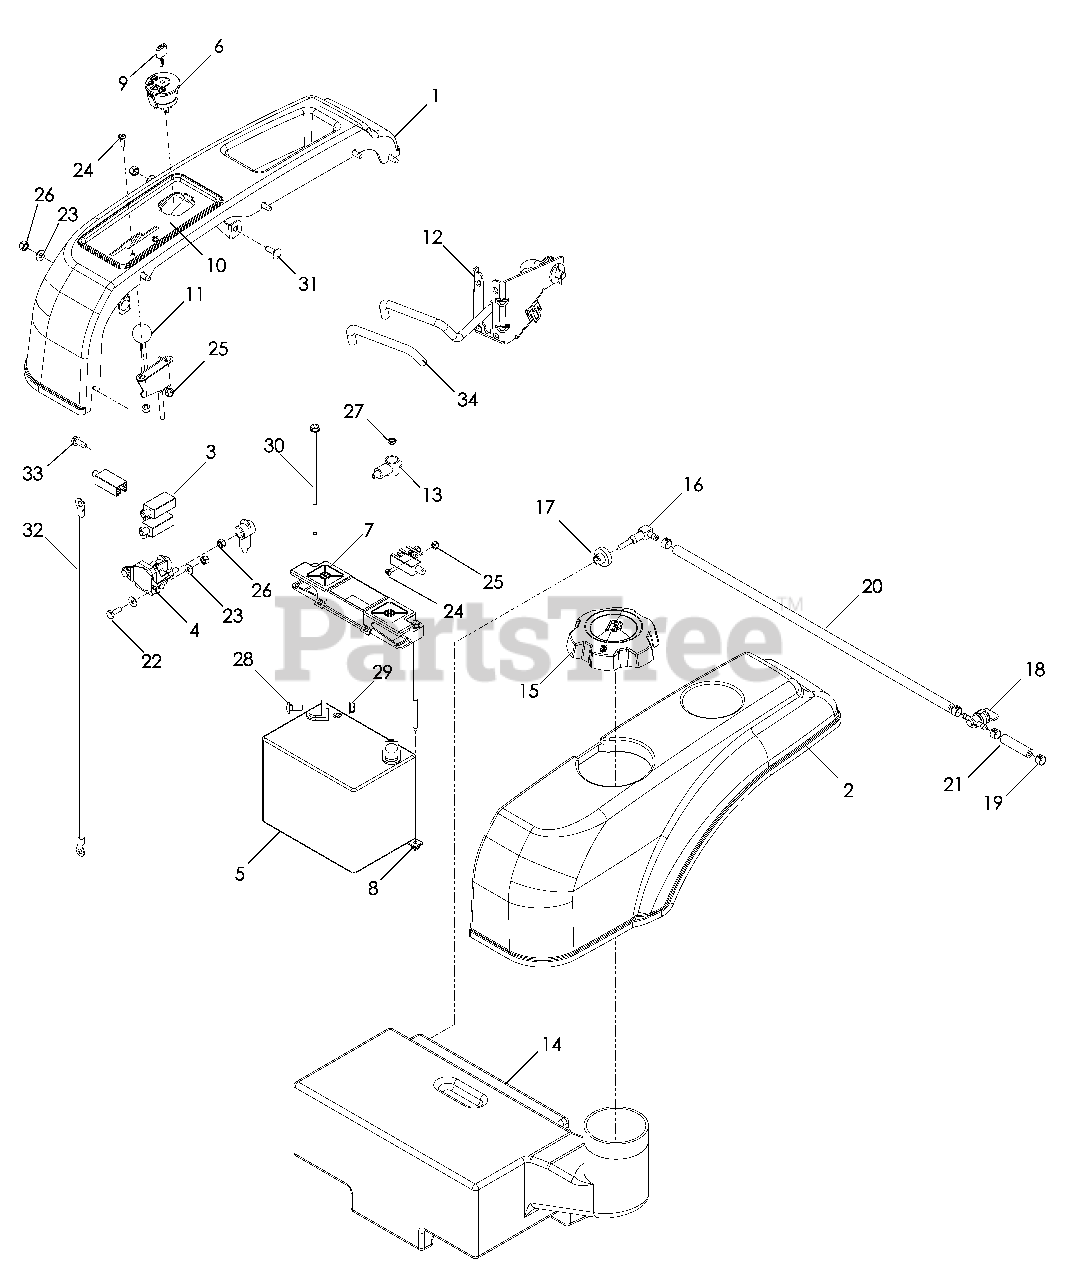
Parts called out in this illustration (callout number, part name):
1	FENDER, RH
2	FENDER, LH
3	SWITCH
4	SOLENOID
5	BATTERY
6	SWITCH, IGNITION
7	BATTERY HOLD DOWN
8	NUT ¼ PUSH NYLON
9	KEY, IGNITION
10	PANEL, CONTROLS
11	CABLE, THROTTLE
12	CABLE, CLUTCH
13	TERMINAL COVER, SM
14	TANK, FUEL
15	CAP, FUEL
16	ELBOW w/ FILTER
17	FITTING, TANK
18	VALVE, FUEL
19	CLAMP, HOSE
20	HOSE ¼ x 21
21	HOSE, ¼ x 2
22	HCS ¼-20 x ¾
23	WASHER ¼ FLAT SAE
24	SCREW #10-24 x 5/8
25	NUT #10-24 HEX NYLOC
26	NUT ¼-20 HEX NYLOC
27	NUT ¼-20 HEX THIN NYLOC
28	RHSNB 5/16-18 x ¾
29	NUT 5/16-18 FLANGE NYLOC
30	BOLT ¼ x 7½
31	RHSNB ¼-20 x ¾ GR2
32	BATTERY CABLE, NEGATIVE
33	SCREW ¼-20 x 5/8 SLF TAP
34	GRIP, CLUTCH
